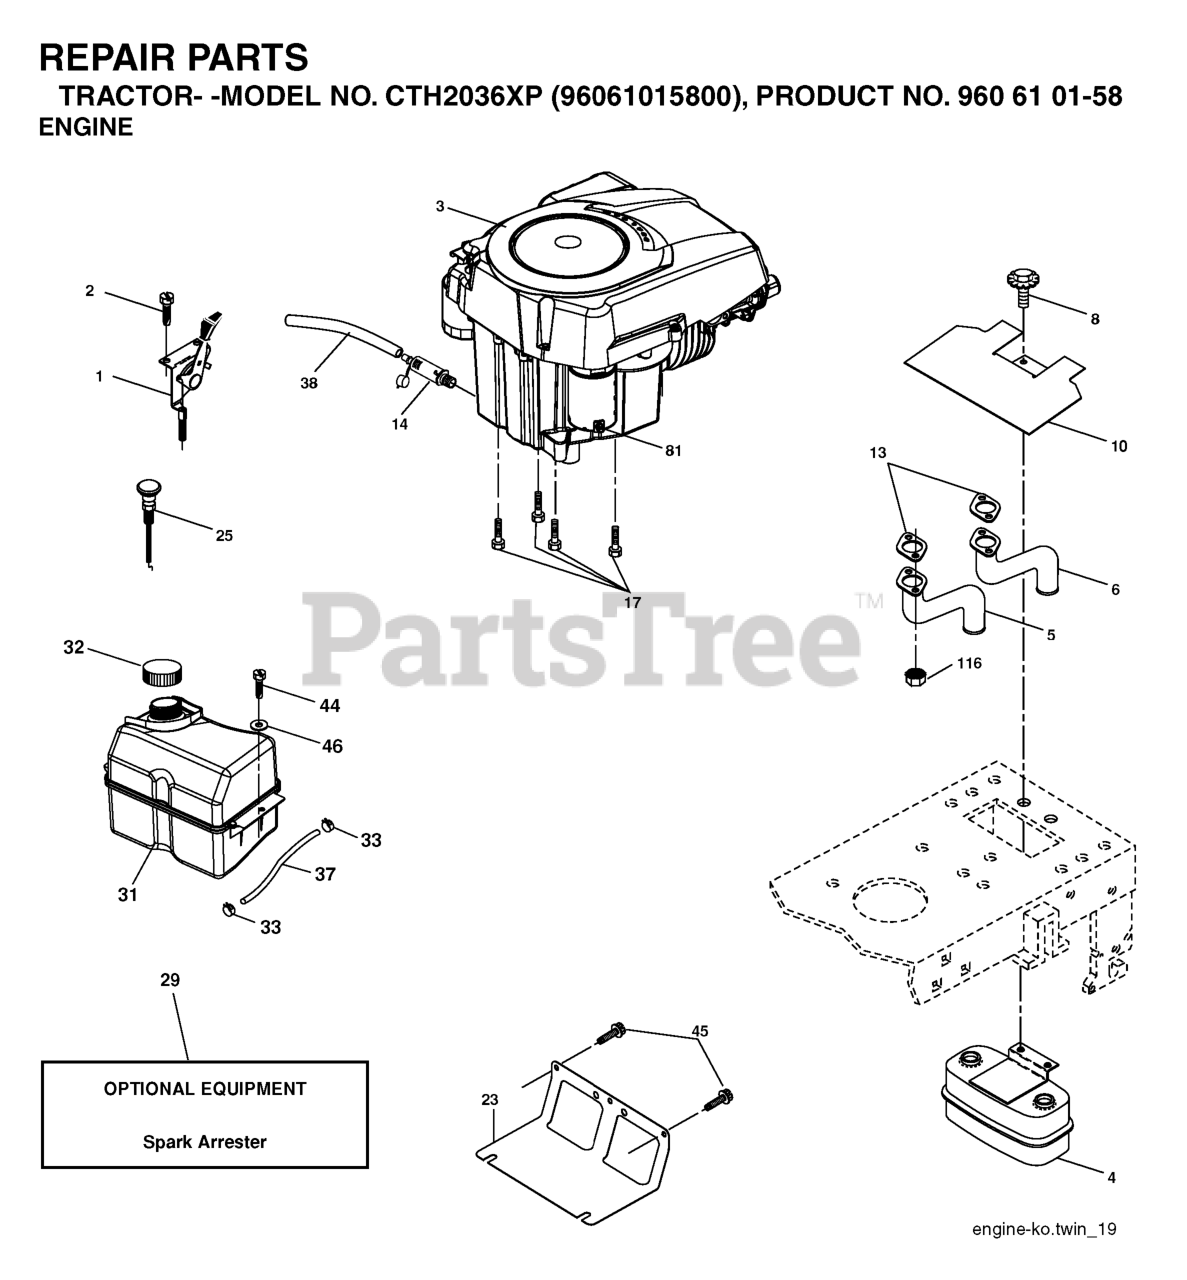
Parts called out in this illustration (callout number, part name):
1	CONTROL.THROTTLE.COBRA.42"BLK.
2	SCREW
4	MUFFLER.TWIN.CYL.LOW.TONE
5	RP.PIPE-EXHAUST LH
6	RP.PIPE-EXHAUST RH
8	BOLT.5/16-18UNCX3/4 W/SEMS.BLK
10	RP SHIELD HEAT MUFFLER
13	GASKET.EXHAUST.KOHLER
14	TUBE, DRAIN OIL ASM.
17	SCREW.3/8-16
23	SHIELD.BROWNING.DBR.GUARD
25	CONTROL, CHOKE
29	KIT.SPARK ARRESTOR 794945 B&S
31	TANK FUEL
32	FUEL CAP
33	HOSE CLAMP
37	LINE.FUEL.20
38	PLUG DRAIN OIL EASY
44	SCREW HEXWSHR 1/4-20X3/4
45	SCREW, 3/8-16X3/4
81	NUT
116	NUT.HEX.FLANGE.TOPLOCK
